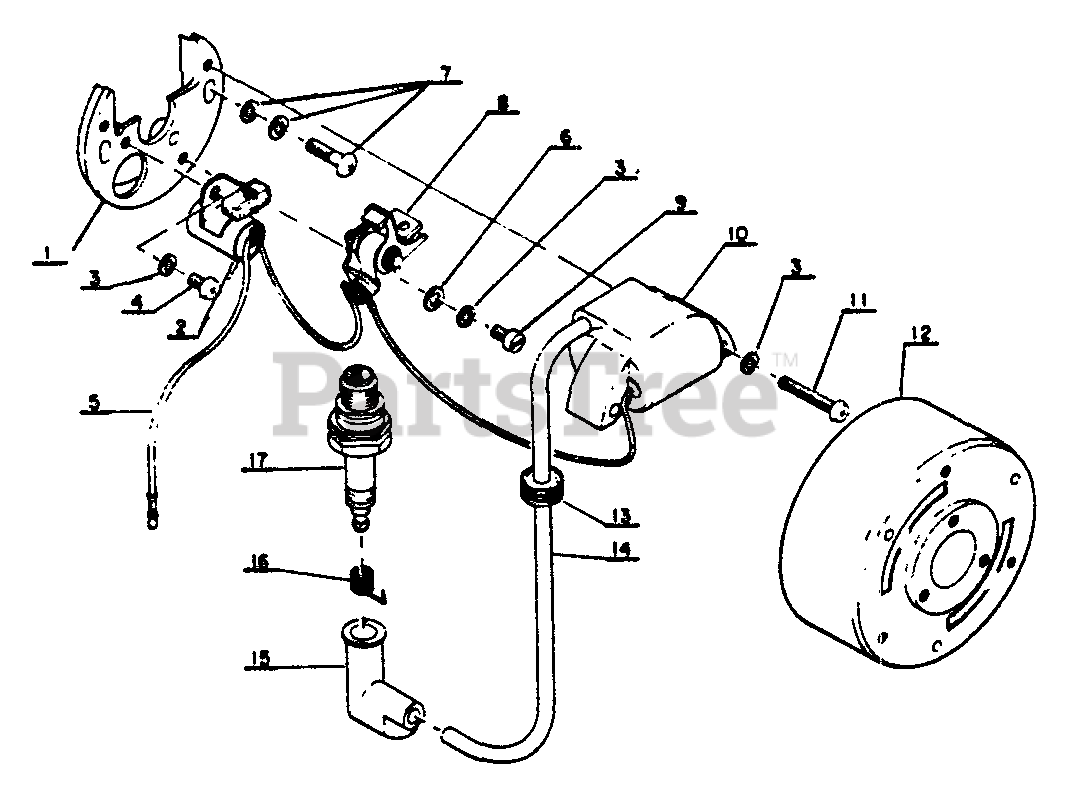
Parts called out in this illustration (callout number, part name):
1	PLATE, STATOR
2	CONDENSER
3	LOCKWASHER - 4
4	SCREW - 4X8
6	WASHER - 4
7	SCREW - 4X16
8	CONTACT POINT SET
9	SCREW - 4X8
10	COIL, IGNITION
11	SCREW - 4X20
12	FLYWHEEL
13	BUSHING
15	CAP, SPARK PLUG
16	TERMINAL, SPARK PLUG CAP
17	SPARK PLUG
